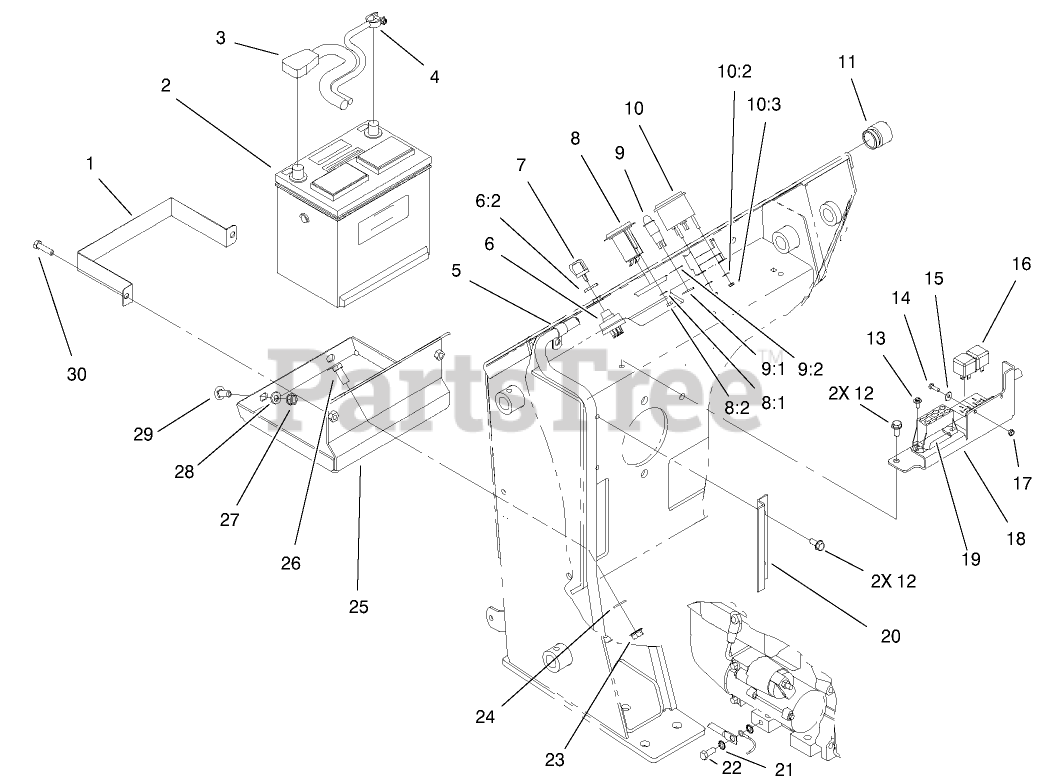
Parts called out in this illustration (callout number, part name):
1	BRACKET-CLAMP, BATTERY
2	BATTERY (DRY)
3	CABLE-BATTERY, POSITIVE
4	CABLE-BATTERY, NEGATIVE
5	CLAMP-R
6	Key Switch ASM
6:2	NUT-HH
7	KEY-IGNITION
8	GAUGE-HOURMETER
8:1	WASHER-LOCK
8:2	NUT-HEX
9	LIGHT-INDICATOR, RED
9:1	NUT-HEX
9:2	WASHER-LOCK
9:3	LED-MINIATURE
10	GAUGE-FUEL
10:2	WASHER-LOCK, INT
10:3	NUT-HEX
11	AUDIO ALARM ASM
12	SCREW-HWHTF
13	SCREW
15	WASHER-PLAIN
16	RELAY
17	NUT-LOCK, NI
18	BRACKET-FUSE/RELAY
19	HARNESS-WIRE
19:1	FUSE-10 AMP
19:2	FUSE-BLADE, 25 AMP
19:3	FUSE-30 AMP
20	SHIELD-WIRING
21	WASHER-LOCK
22	SCREW-HHF
23	NUT-HF
24	WASHER-FLAT
25	BATTERY TRAY ASM
26	SCREW-HH
27	NUT-LOCK, NI
28	WASHER-FLAT
29	SCREW-CARR
30	SCREW-HH
